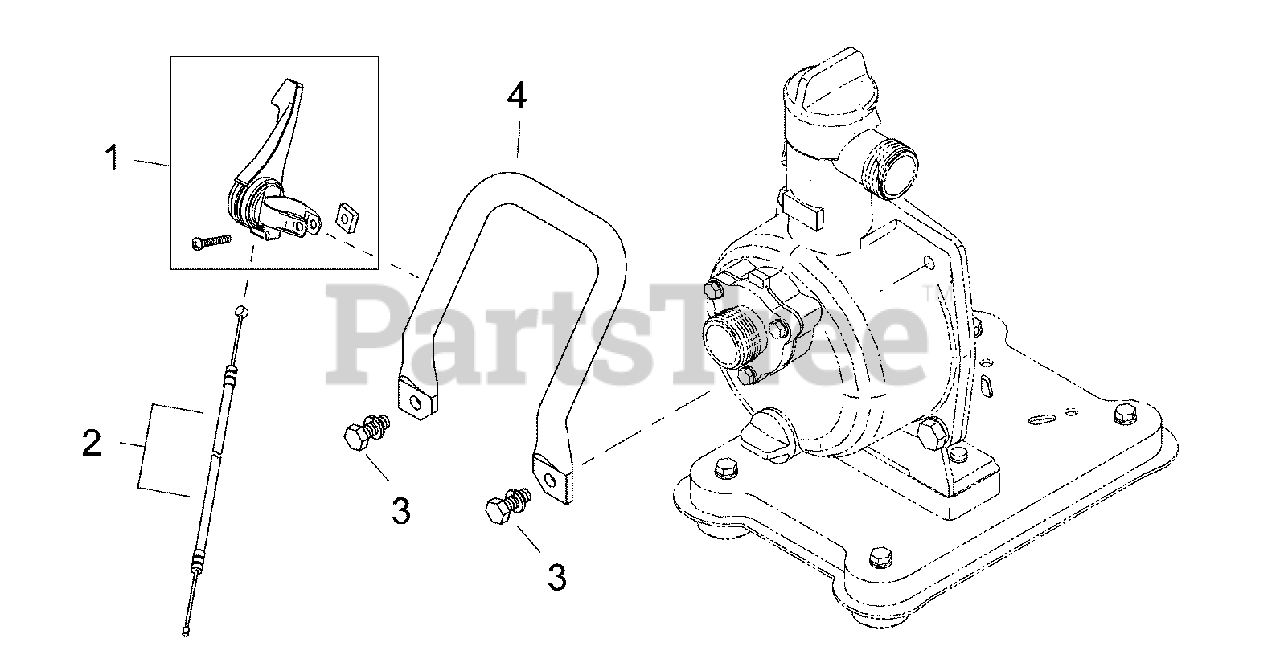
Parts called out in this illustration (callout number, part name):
1	THROTTLE CONTROL ASSY
2	CABLE, THROTTLE
3	BOLT M8×22
4	HANDLE
